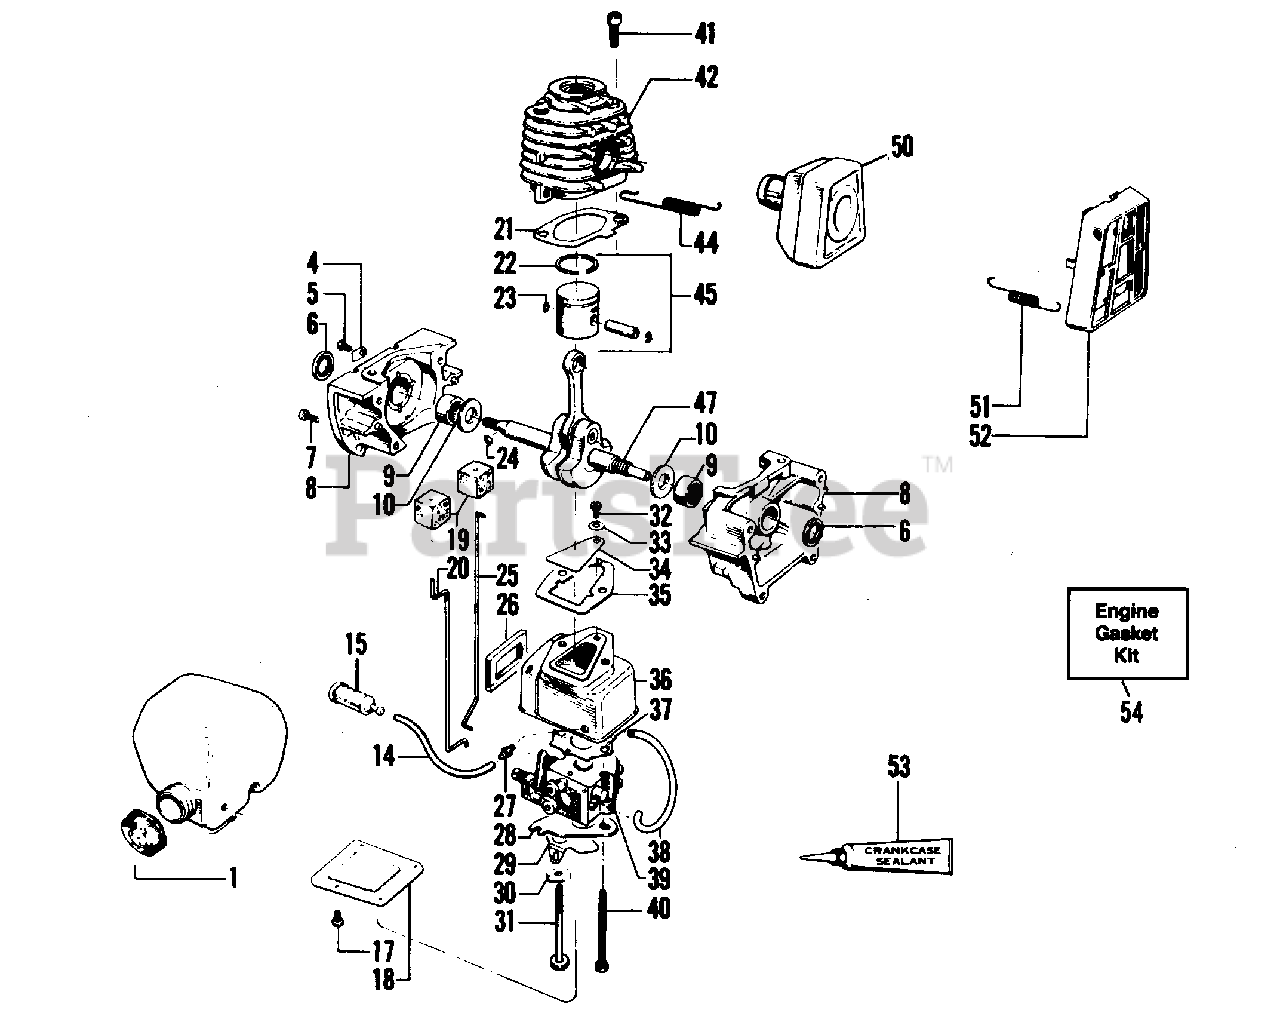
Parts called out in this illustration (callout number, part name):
1	Fuel Cap Ass'y (Incl. O-Ring)
4	Clamp - Choke Wire
5	Screw - Choke Rod Clamp (Pan. Hd. 8 - 32 x 5/16)
6	Seal - Crankcase
7	Screw - Crankcase (Fil. Hd. 10 - 24 x 5/8)
8	Crankcase Ass'y. (Incl. 6, 9 & Qty. 1 of #7)
9	Bearing - Crankcase
10	Washer - Thrust - Crankcase
11	Fuel Tank Ass'y. (Incl. 3, 14, 15, 16 & 27)
14	Fuel Line - Type 1
14	Line Kit - Type 2
15	Type 2
17	Screw - Carburetor Case Cover (Pan Hd. 8 - 18 x 9/16)
18	Cover Carburetor Case
19	Boot - Throttle - Choke Wire
20	Choke Wire
21	Gasket - Cylinder
22	Ring - Piston
23	Retainer - Wrist Pin
24	Key - Flywheel
25	Throttle Wire
26	Seal - Carburetor Case
28	Choke Wire Guide Plate
29	Choke Shutter
30	Washer - Wave
31	Screw - Carburetor Shoulder (Fil. Hd. 10 - 24 x 2 1/8)
32	Screw - Reed Valve (Pan. Hd. 6 - 19 x 5/16)
33	Washer - Reed Valve Screw (Flat No. 6)
34	Reed Valve
35	Gasket - Carburetor Case to Crankcase
36	Carburetor Housing
37	Gasket - Carburetor
38	Line Kit
39	Carburetor - WA - 149 (see pg. 4 for assembly)
40	Screw - Carburetor (Fil. Hd. 10 - 24 x 1 -7/8)
41	Screw - Cylinder (Soc. Hd. 1/4 - 20 x 3/4)
42	Type 2
44	Spring - Muffler Detachment
45	Piston Kit (Incl. 22,23)
47	Crankshaft & Rod Ass'y.
51	Spring - Muffler Guard
52	Guard - Muffler
53	Sealant - Crankcase
54	Engine Gasket Kit
